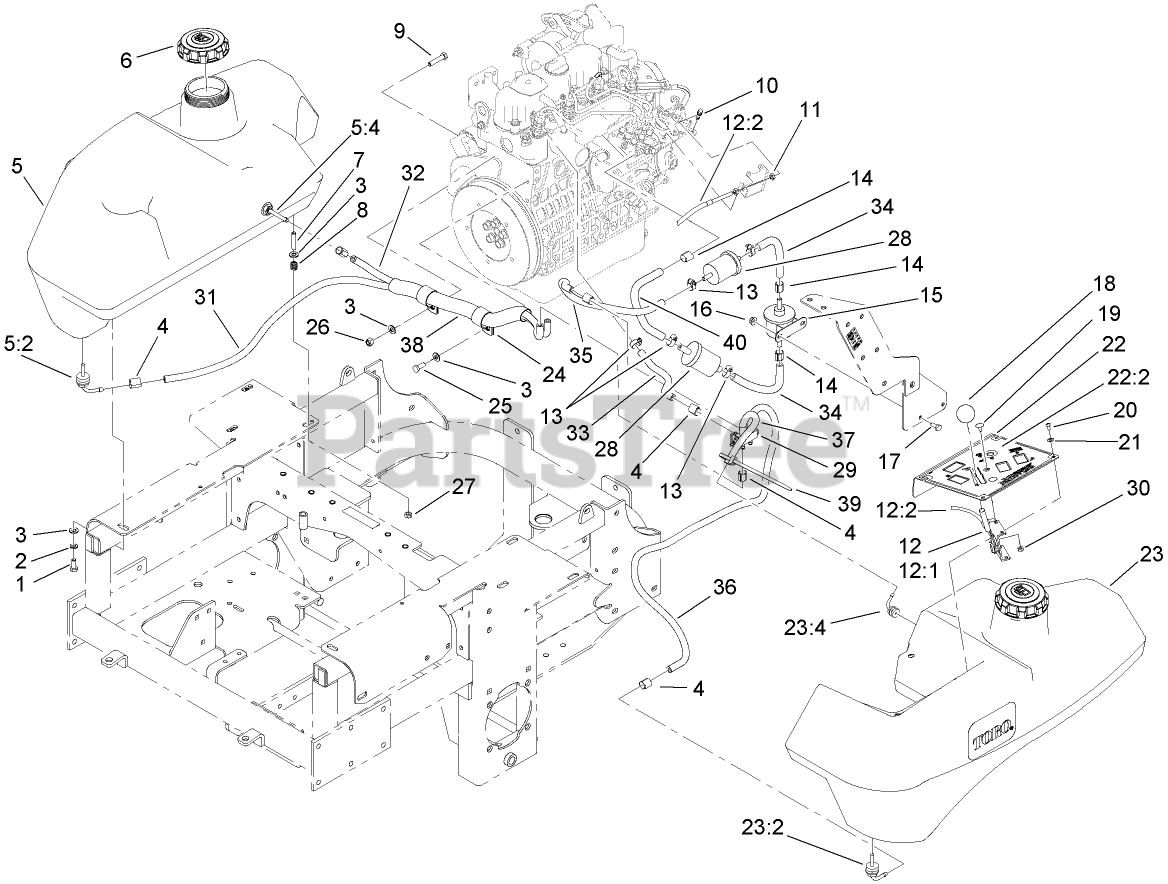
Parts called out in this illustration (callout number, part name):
1	SCREW-HH
2	WASHER-LOCK
3	WASHER-PLAIN
4	CLAMP-HOSE, FUEL
5	RH FUEL TANK ASM
5:2	FITTING-FUEL, BULKHEAD
5:4	Fitting-Fuel, Bulkhead
6	CAP-FUEL, DIESEL
8	SPRING-TANK, FUEL
9	SCREW-HH
10	SWIVEL-STOP, CABLE
11	NUT-JAM
12	THROTTLE CONTROL ASM
12:1	LEVER-THROTTLE
12:2	CABLE-THROTTLE
13	CLAMP-WORM
14	CLAMP-HOSE, FUEL
15	PUMP-FUEL, ELECTRIC
16	NUT-HF
17	SCREW-HH
18	KNOB-BALL
19	BOLT-CARR
20	SCREW-PPH
21	WASHER-SPRING
22	CONTROL PANEL ASM
22:2	DECAL-PANEL, CONTROL
23	LH FUEL TANK ASM
23:2	FITTING-FUEL, BULKHEAD
23:4	Fitting-Fuel, Bulkhead
24	CLIP-LOOM
25	SCREW-HH
26	NUT-LOCK, NI
27	NUT-LOCK, NI
28	FILTER-FUEL
29	VALVE-FUEL, DUAL FLOW
30	NUT-LOCK, NI
31	HOSE-FUEL
32	HOSE-FUEL
33	HOSE-FUEL
34	HOSE-FUEL
35	HOSE-FUEL
36	HOSE-FUEL
37	HOSE-FUEL
38	SLEEVE-FABRIC
39	TIE-PLASTIC
40	HOSE-FUEL
